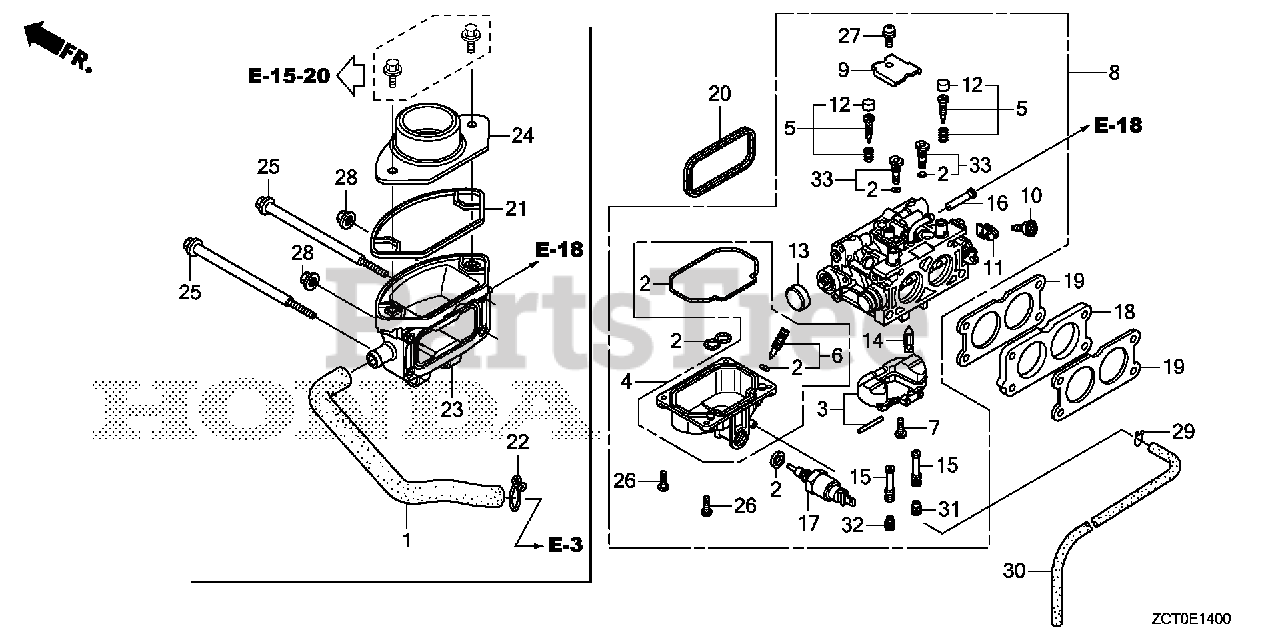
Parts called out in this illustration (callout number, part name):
1	TUBE, BREATHER
2	GASKET SET
4	CHAMBER SET, FLOAT
6	SCREW SET, DRAIN
7	SCREW, FLOAT
8	CARBURETOR ASSY. (BK06H B)
8	CARBURETOR ASSY. (BK06H C)
10	SCREW, THROTTLE STOP
11	ARM, THROTTLE LINKAGE
12	CAP, ADJUSTING SCREW
13	CAP, CHOKE DUST
14	VALVE, FLOAT
15	NOZZLE, MAIN
16	SCREEN, FUEL STRAINER
17	VALVE ASSY., SOLENOID
18	INSULATOR, CARBURETOR
19	GASKET, CARBURETOR
20	GASKET, AIR CLEANER
21	SEAL, AIR CLEANER HOUSING
22	CLIP, BREATHER TUBE
23	ELBOW, AIR CLEANER
24	JOINT, CONNECTING TUBE
25	BOLT, FLANGE (6X106)
26	SCREW, PAN (4X12)
27	SCREW-WASHER (5X10)
28	NUT, FLANGE (6MM)
29	CLIP, TUBE (B8)
30	BULK HOSE, VACUUM (4.5X1000) (4.5X350)
31	JET, MAIN (#105)
31	JET, MAIN (#100)
31	JET, MAIN (#112)
32	JET, MAIN (#105)
32	JET, MAIN (#100)
32	JET, MAIN (#112)
33	JET SET, PILOT (#40)
